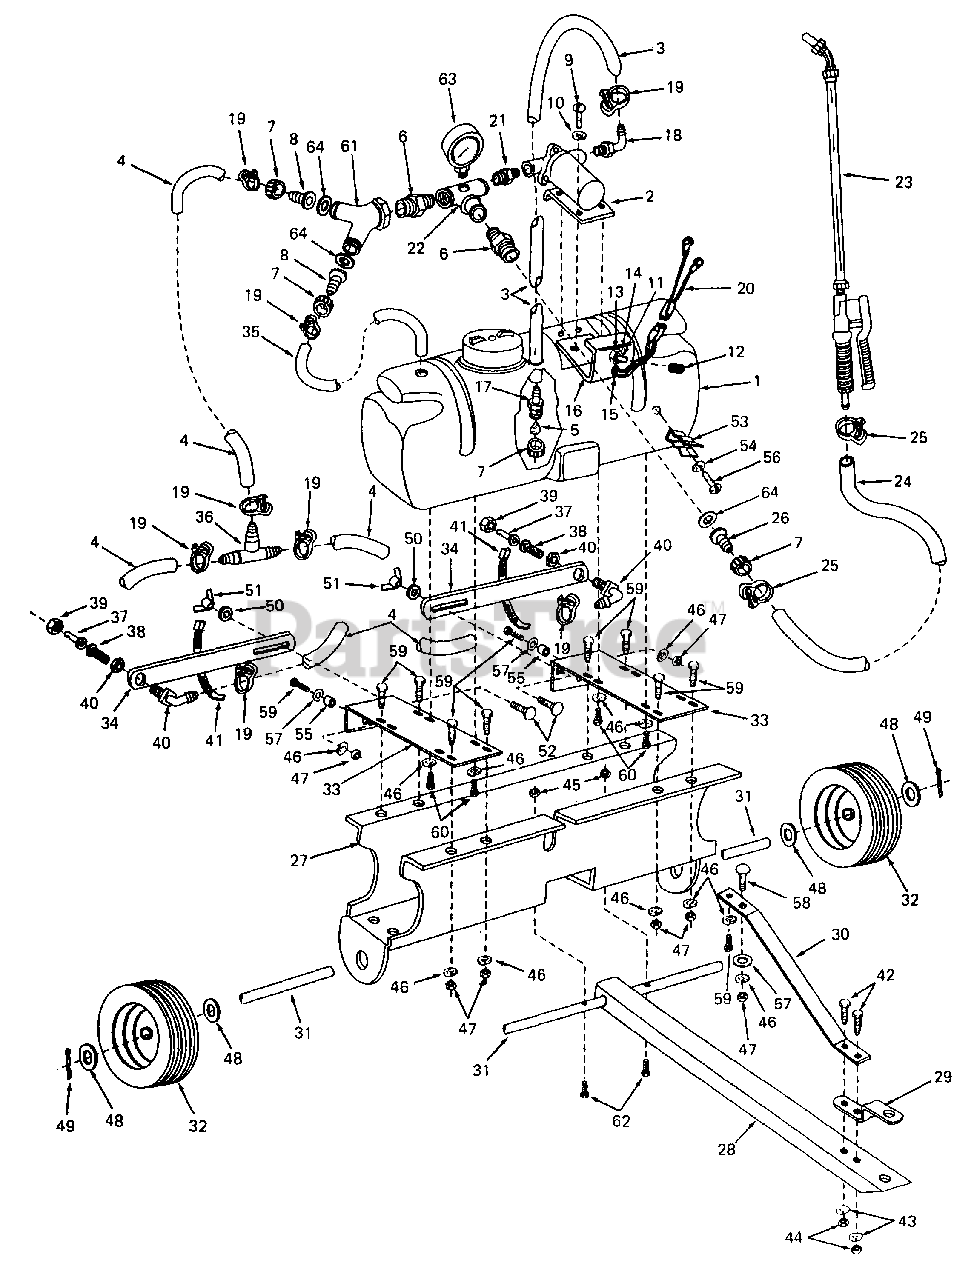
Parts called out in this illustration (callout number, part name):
1	Tank w/Cap, 14 Gallon
2	Pump, Motor/w
3	Hose, 1/2 ID X 24" Lg
4	Hose, 1/2 ID X 20" Lg
6	Adapter, 1/2 NPT X Hose
7	Nut, Swivel 3/4 Hose
8	Barb, 1/2 Hose
9	Screw, Pan Hd, #10-24 X 1 Lg
10	Washer, Flat
11	Switch, On-Off
12	Boot, Rubber
13	Plate, Switch
14	Nut, Switch
16	Bracket, Switch Mtg
17	Adapter, 3/4 Hose X 1/2 Barb
18	Elbow, 3/8 NPT X 1/2 Barb
19	Clamp, 1/2
20	Harness, Battery
21	Nipple, 1/2 X 3/8 Nylon
23	Gun, Spray
24	Hose, 3/8 ID X 12'-6" Lg
25	Clamp, 3/8
26	Barb, 3/8 Hose
30	Brace, Hitch
33	Bracket, Tank Mtg
34	Bar, Boom
35	Hose, 1/2 ID X 14" Lg
37	Nozzle, SS Floodjet
38	Strainer, Screen Type
39	Nut, Screen Body
41	Tie, Cable
42	Screw, Hex Cap, 3/8-16 X 1.25 Lg GR5
43	Washer, Lock, 3/8
44	Nut, Hex Center Lock, 3/8-16
45	Nut, Hex Center Lock, 1/4-20
46	Washer, Lock, 5/16
47	Nut, Hex, 5/16-18
48	Washer, Flat, .781 X 1.59 X .065 Thk
49	Pin, Cotter, 1/8 X 1.50 Lg
50	Washer, Flat, 1/4
51	Nut, Wing Lock, 1/4-20
52	Bolt, Carriage, 114 X .75 Lg
53	Clip, Hose
54	Washer, Lock, #10
55	Bushing, Pivot
56	Screw, Slot Hd, #10-24 X .50 Lg
57	Washer, 5/16
58	Bolt, Carriage, 5/16-18 X .75 Lg
59	Screw, Hex Cap, 5/16-18 X .75 Lg
60	Screw, Hex Cap, 5/16-18 X .50 Lg
61	Connector, Y
62	Screw, Hex Cap, 1/4-20 X 1.50 Lg
63	Gauge, Pressure, 100 PSI
64	Gasket, 3/4 Hose
